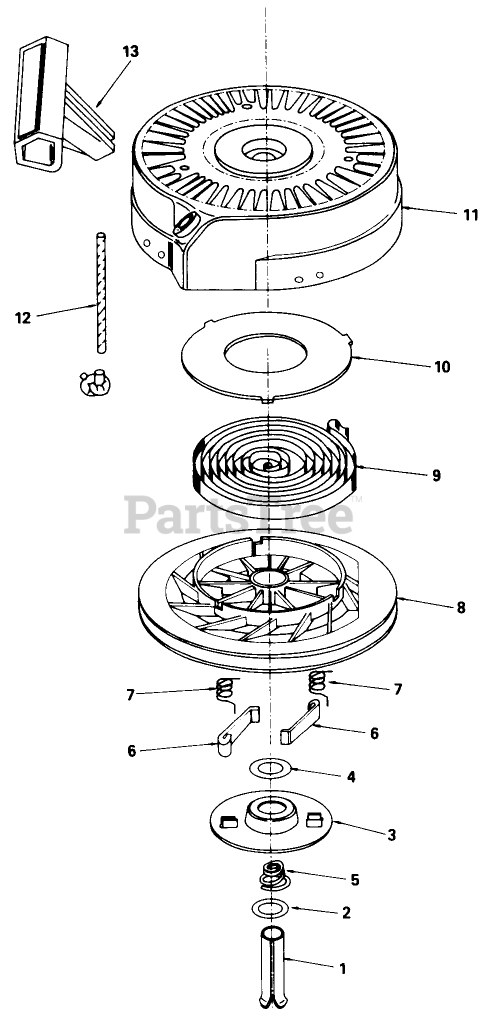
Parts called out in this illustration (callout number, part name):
1	Pin, Spring (Incl. Ref. #7)
2	Washer
3	Retainer
4	Washer
5	Brake Spring
6	Dog-Starter
7	Spring-Dog
8	Pulley
9	Rewind Spring
10	Cover-Spring
11	Housing-Starter
12	Rope-Starter (98 cut to length)
13	Handle-Starter
